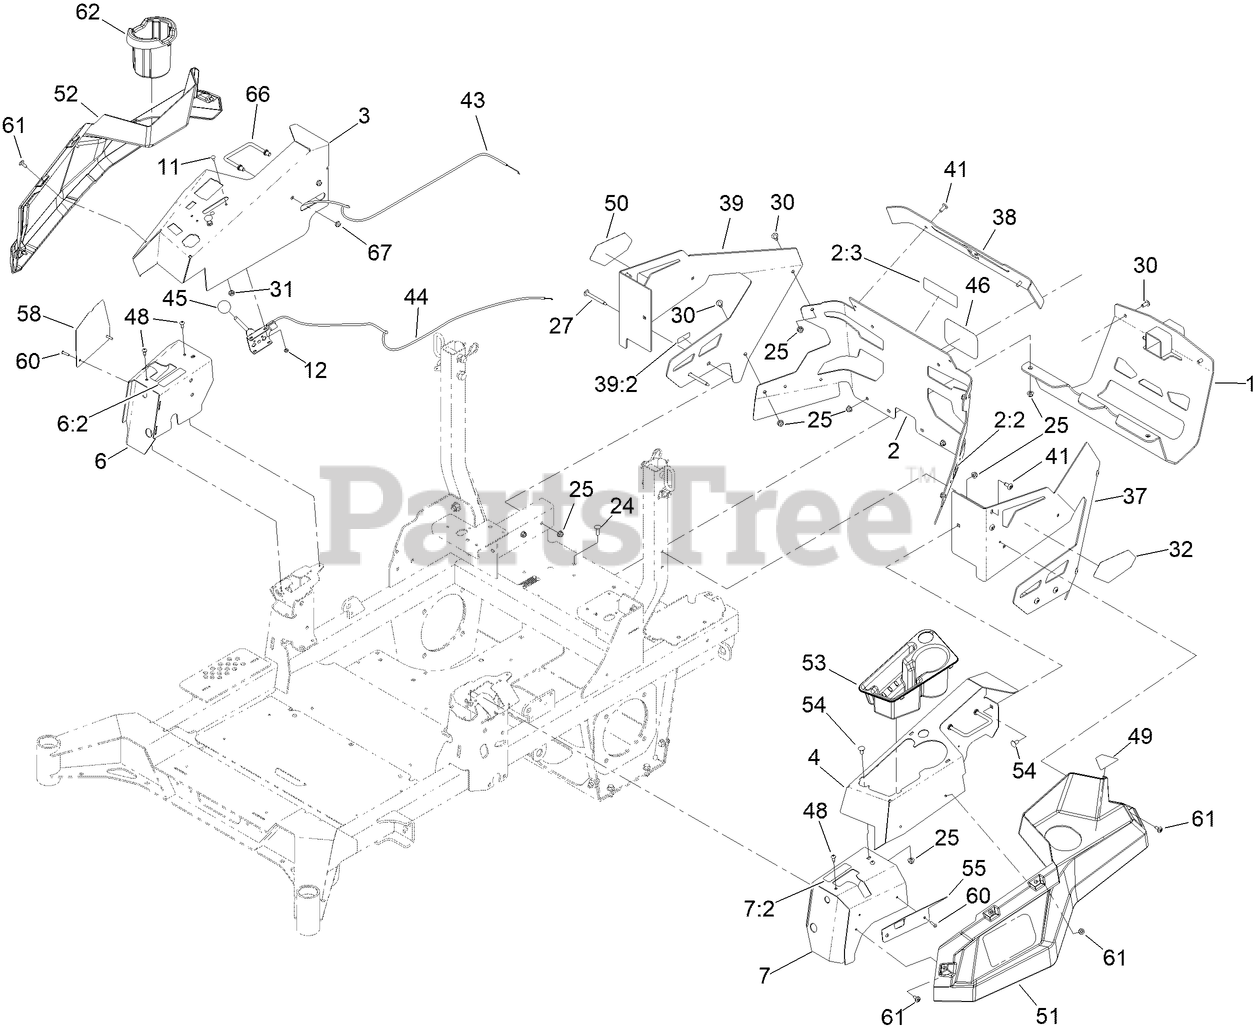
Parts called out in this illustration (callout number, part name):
1	MUFFLER GUARD ASM [BLACK]
2	REAR GUARD ASM
2:2	DECAL-WARNING
2:3	DECAL-HITCH
3	CONSOLE-RH
4	CONSOLE-LH
6	RH COVER ASM
6:2	DECAL-CONTROL, MOTION
7	LH COVER ASM
7:2	DECAL-CONTROL, MOTION
11	BOLT-CARR
12	NUT-LOCK, NI
24	SCREW-CARR
25	NUT-HF, NI
27	SCREW-TORX
30	SCREW-TORX
31	NUT-HJ
32	DECAL - 4000 SERIES, LH
37	GUARD-REAR, LH
38	GUARD-REAR, TOP
39	RH REAR GUARD ASM
39:2	DECAL-ARRESTOR, SPARK
43	CABLE-CONTROL, CHOKE
44	CABLE-CONTROL, THROTTLE
45	KNOB-BALL
48	SCREW-TPH THD FORM
49	DECAL-FILL, FUEL
50	DECAL-4000 SERIES, RH
51	SIDE POD, LH
52	SIDE POD, RH
53	CUP HOLDER
54	SCREW-CARR
55	PLATE-COVER, LH FRONT
58	PLATE-COVER, RH FRONT
60	RIVET-TRIFOLD
61	SCREW-SHOULDER
62	CUPHOLDER-RH
66	ROD-SUPPORT, POD
